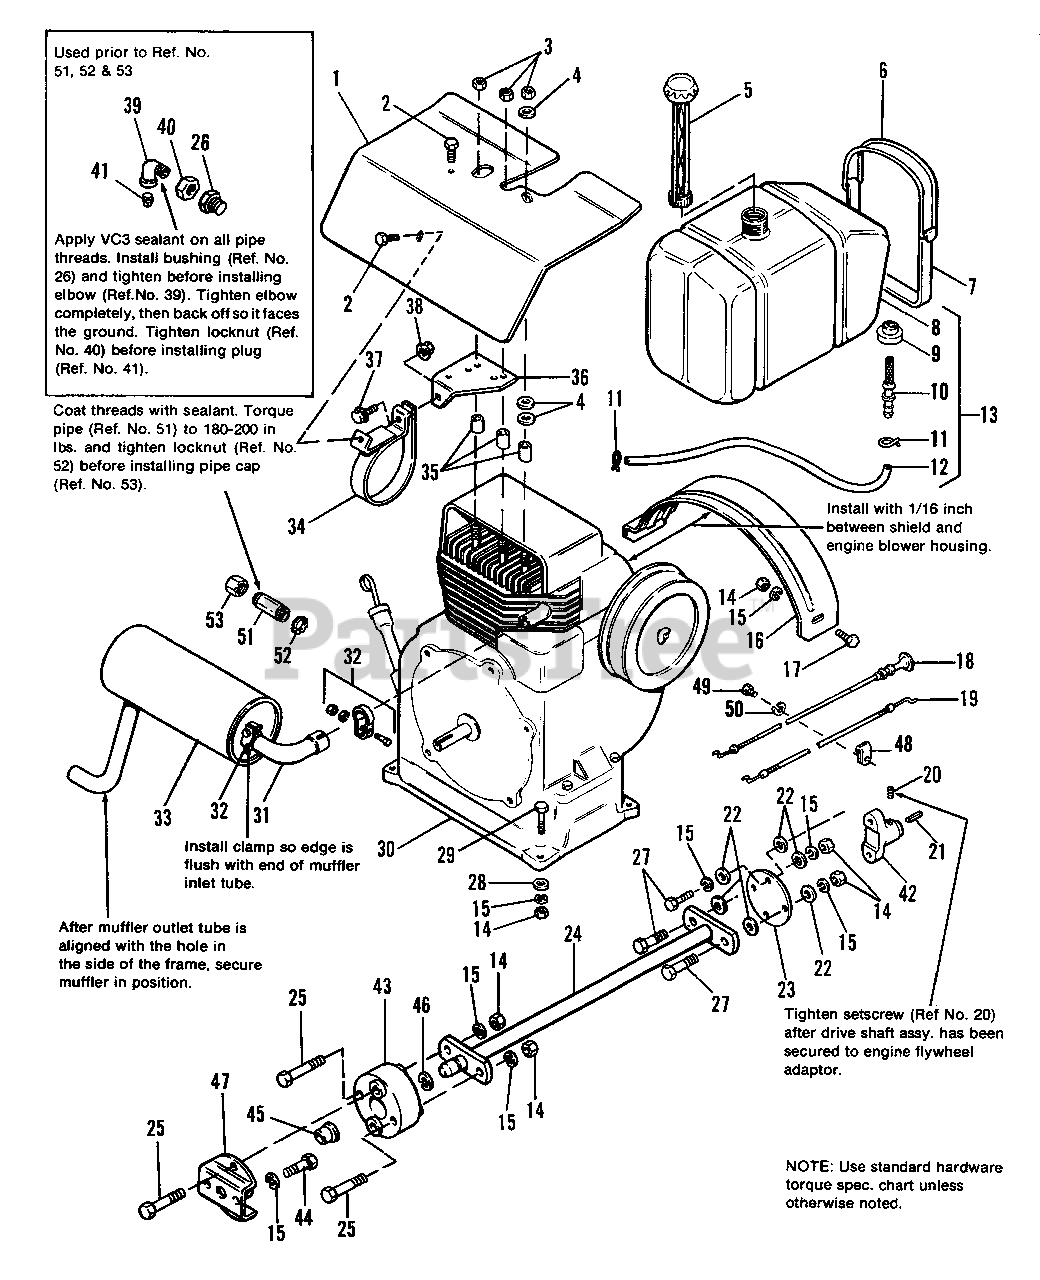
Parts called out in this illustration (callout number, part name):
1	SHIELD, Heat
2	SCREW, Hex, Taptite, 1/4-20 x 1/2
3	LOCKNUT, Hex, Jam, 3/18-6
5	CAP, Fuel Tank
6	STRAP, Fuel Tank
7	STRAP, Tank
11	CLAMP, Hose
13	TANK ASSY., Fuel
14	NUT, Hex, Full, 3/8-16
15	LOCKWASHER, 3/8
17	CAPSCREW, Hex Hd., 3/8-16 x 1
18	CONTROL, Choke
19	CONTROL, Throttle
20	SETSCREW, 3/8-24 x 3/8
21	KEY, Drive Shaft
22	WASHER, Special
24	SHAFT ASSY., Drive
25	CAPSCREW, Hex Hd., 3/8-16, 2-1/2
26	BUSHING, Pipe, 3/4 x 3/8
27	CAPSCREW, Hex Hd., 3/8-16 x 1-1/4
28	WASHER, Plain, 3/8
29	CAPSCREW, Hex Hd., 3/8-16 x 1-1/2
30	ENGINE, 12 HP Kohler
31	ELBOW, Exhaust
32	CLAMP, Muffler
33	MUFFLER, Exhaust
34	STRAP ASSY., Muffler
36	SUPPORT, Muffler
37	CAPSCREW, Hex, Whiz, Flange, 5/16-18 x 1-1/2
38	NUT, Hex, Whiz, Flange, 5/16-18
39	ELBOW, Pipe, 90ø, 3/8
40	LOCKNUT, 3/8-18
41	PLUG, Pipe, 3/8
42	FLANGE, Drive Shaft
43	COUPLING, Compression
44	CAPSCREW, Hex Hd., 3/8-16 x 3/4
46	RING, Retaining
47	PLATE ASSY., Adaptor
48	CLIP, Control Cable
49	CAPSCREW, Flex, 1/4-20 x 1/2
50	LOCKWASHER, 1/4
51	DRAIN, Oil
52	LOCKNUT, 3/4
53	CAP, Hex 3/4
